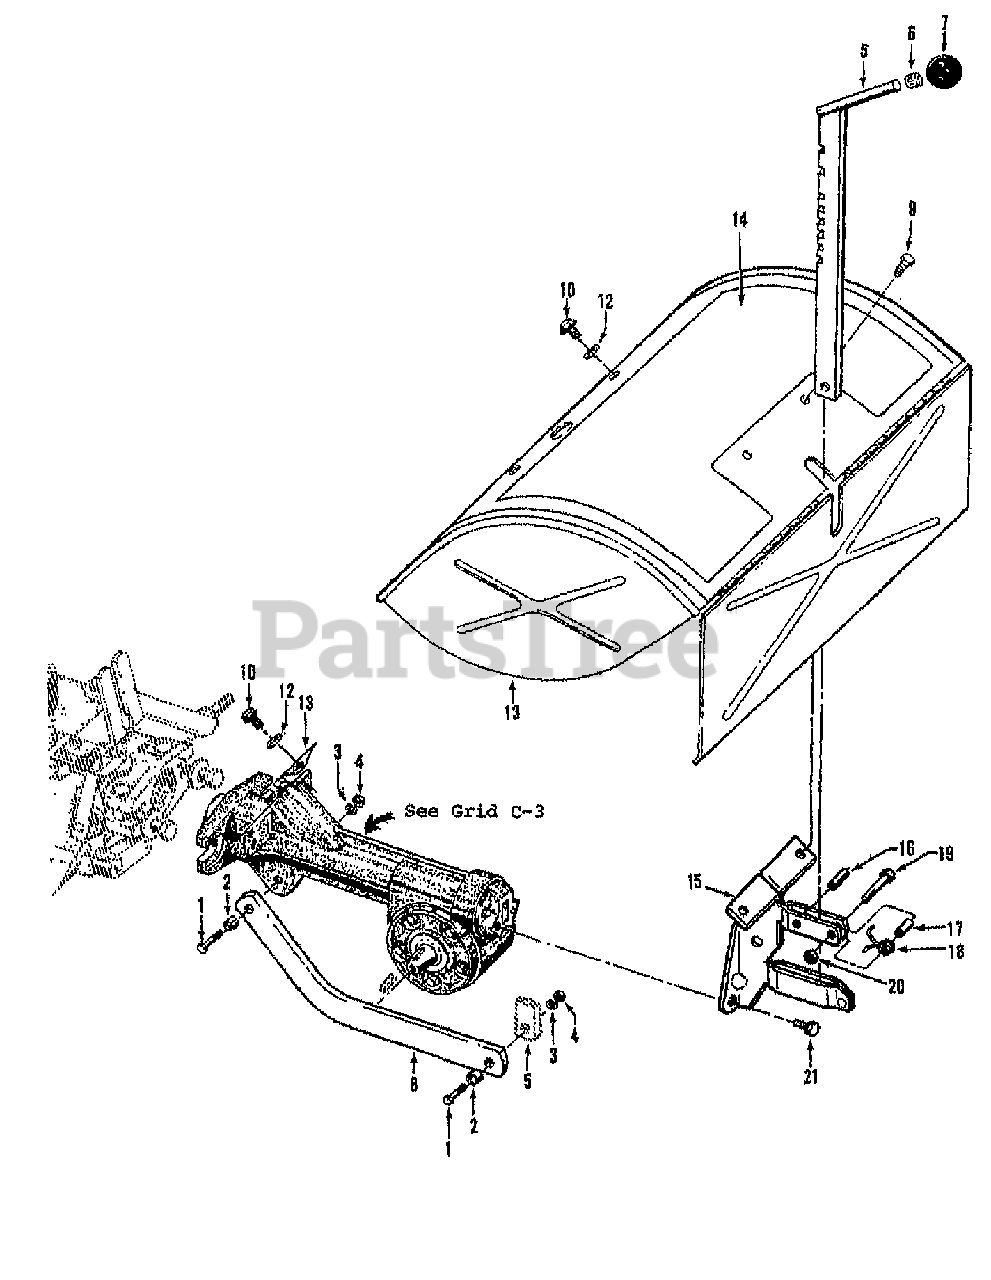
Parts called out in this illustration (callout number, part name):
1	SCR-HH 3/8-16X1.25
2	BUSHING-.5X.375X.3
3	WASHER-LK .375 @ DEPL
4	NUT-HEX 3/8-16 ZP
5	DEPTH REGULATOR W/KNOB
6	RING-TOLERANCE .5325 ID
7	KNOB-CONTROL
8	BAR-DRAG RED
9	SCR-HWH 1/4-20 X .5 STH
10	SCR-HFLK 5/16-18X.75 ZP
12	WASHER-#1.125X.344 ZP
13	HOOD W/DECALS OPC SERVICE
14	DECAL-HOOD INST
15	BRKT W/ROLL PIN (9308)
16	PIN-ROLL .25 X 1
17	SPACER-.250X.343X.375
18	SPRING-TORSION
19	SCR-HH 1/4-20X1.0
20	NUT-LK 1/4-20
21	SCR-HFLK 5/16-18X.62 G5ZP
